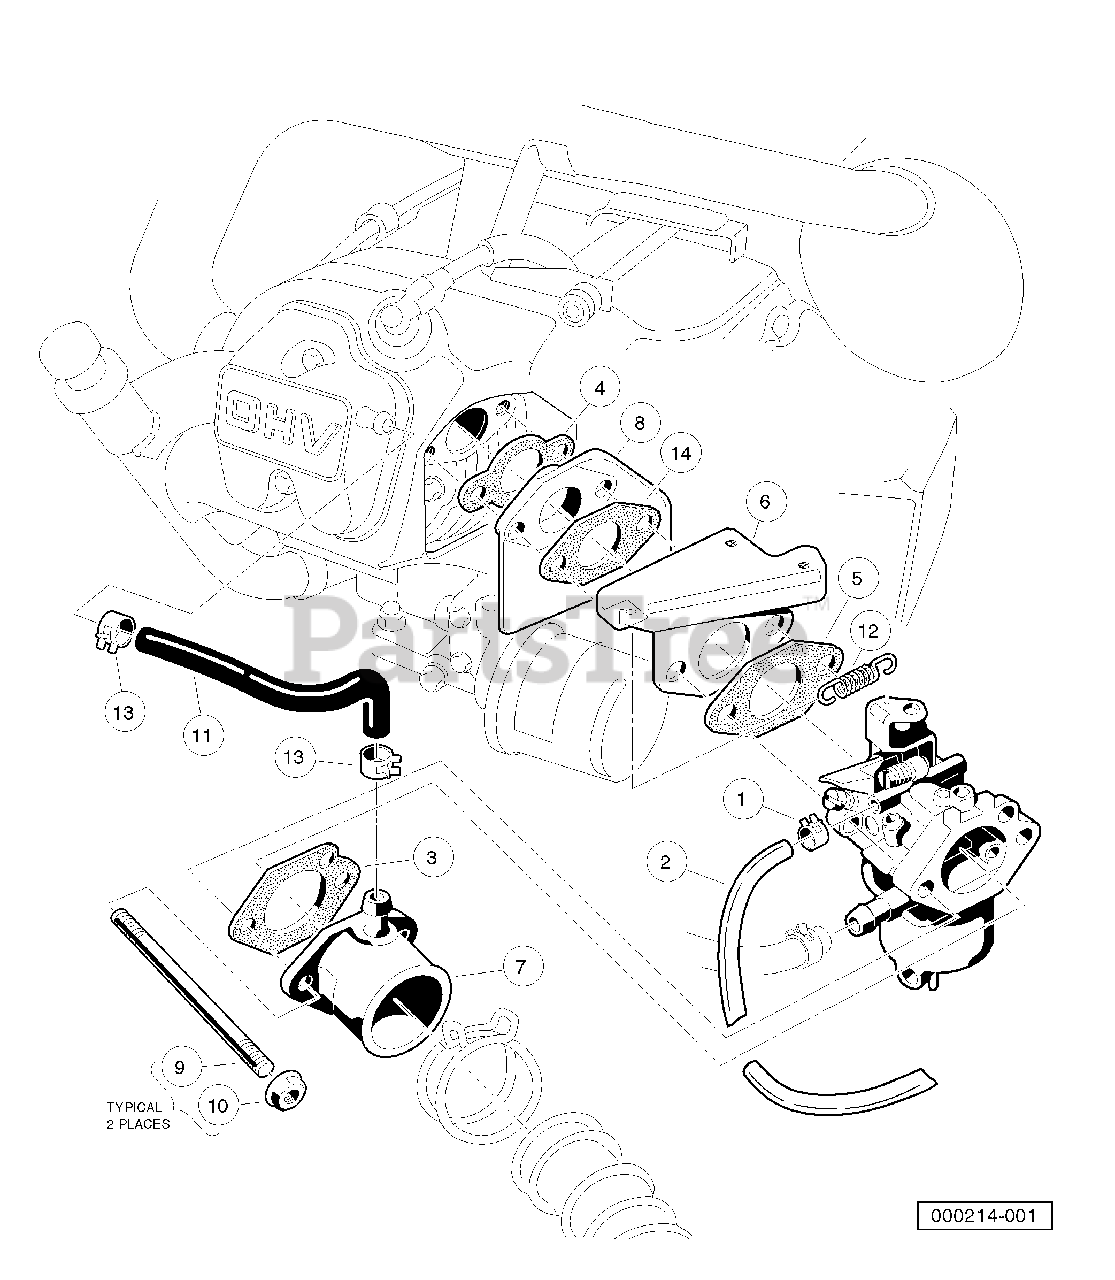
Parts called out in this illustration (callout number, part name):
1	Clamp, 0.301 ID Hose
2	Fuel Line
3	Gasket, Carb To Intake Manifold
4	Gasket, Engine to Insulator
5	Gasket, Sprg Brkt To Carb OHV
6	Bracket, Throttle Spring Return
7	Pipe, Intake Manifold
8	Insulator, Carburetor
9	Stud, M6-1.00 Two-Ended
11	Tube, Crankcase Vent
12	Spring, Throttle Return
14	Gasket, Insulator To Bracket
